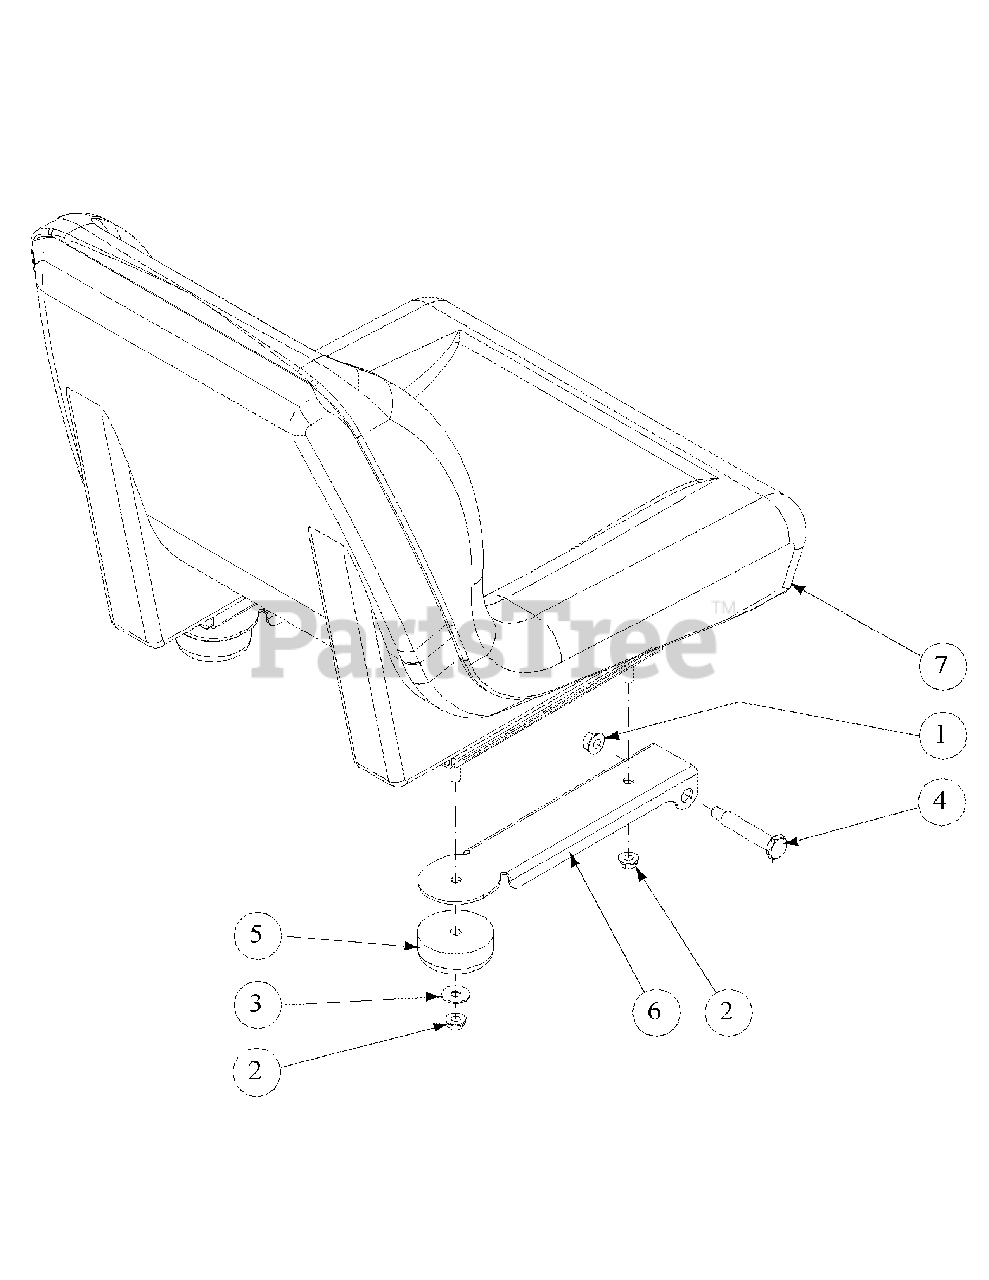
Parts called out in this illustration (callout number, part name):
1	Flange Lock Hex Nut, 3/8-16
2	Hex Flange Lock Nut, 5/16-18
3	Belle Washer, .325 x .930 x .045
4	Shoulder Screw, .50x2.345, 3/8-16
5	Grommet, 2.5 OD x 1.0 Long
6	Seat Mounting Bracket
